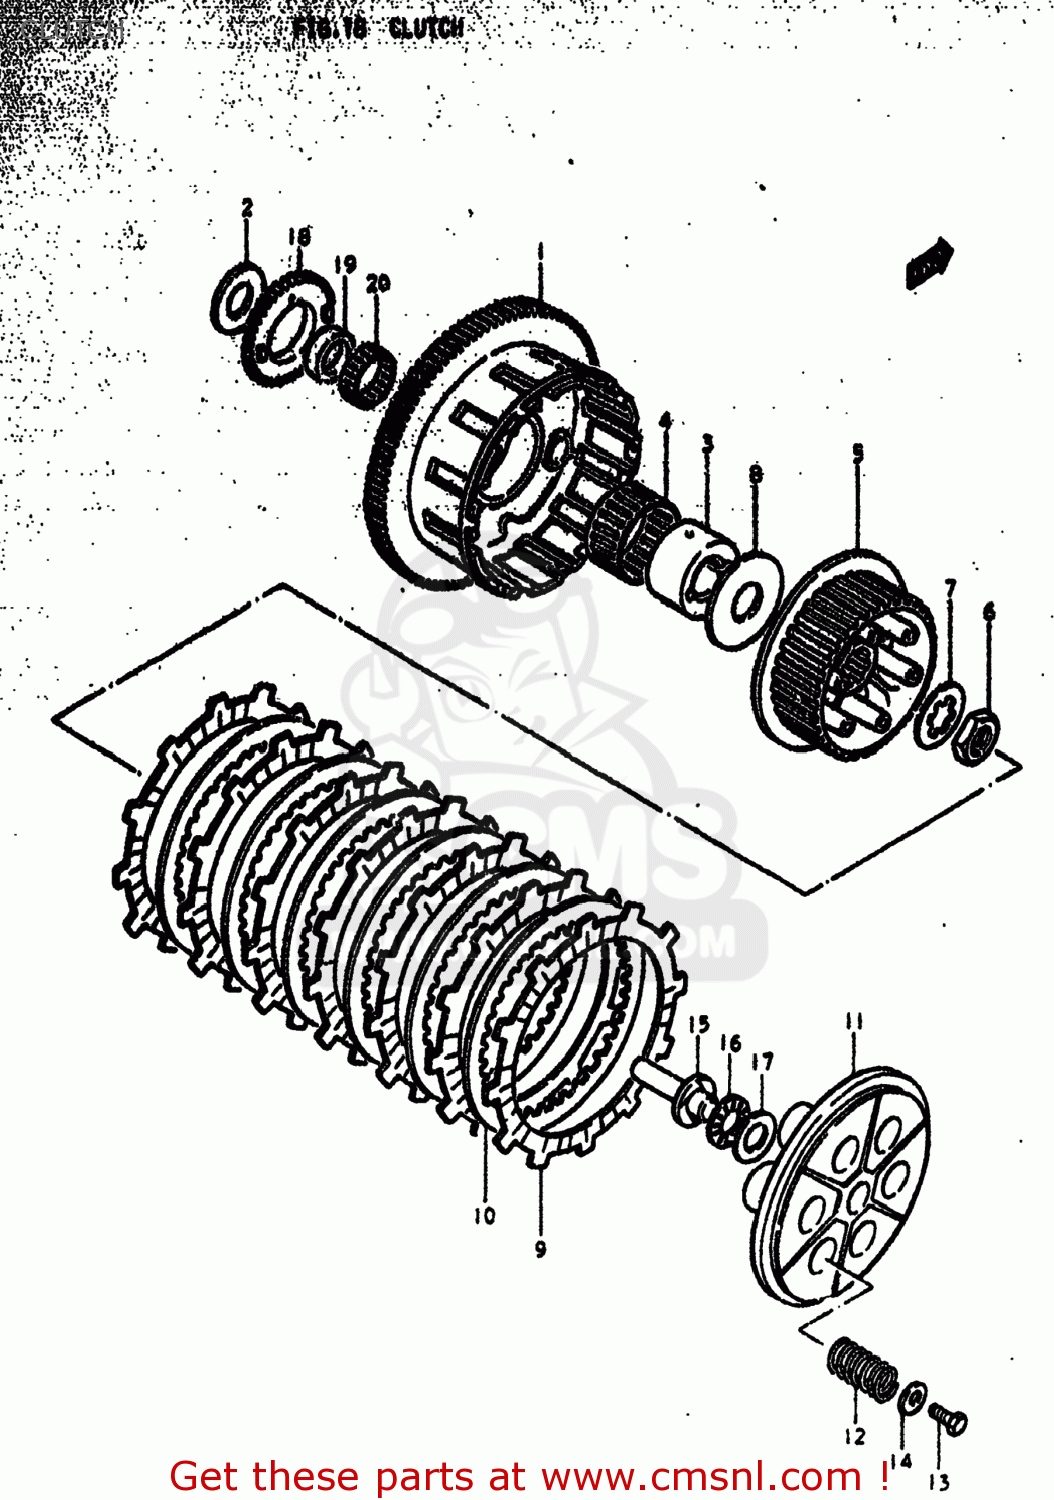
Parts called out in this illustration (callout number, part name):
1	GEAR ASSEMBLY,PRIMARY DRIVE
2	WASHER
3	SPACER,PRIMARY DRIVEN
4	BEARING
5	HUB,CLUTCH SLEEVE
6	NUT
7	WASHER,LOCK
8	WASHER(25X66X3.5)
9	PLATE,CLUTCH DRIVE (NAS)
10	PLATE,CLUTCH DRIVEN (NAS)
11	DISC,CLUTCH PRESSURE
12	SPRING
13	BOLT, UPPER
14	WASHER
15	PIECE,CLUTCH PUSH
16	BEARING(15X28X2)
17	WASHER
18	GEAR,OIL PUMP DRIVE
19	SPACER,OIL PUMP DRIVE GEAR
20	BEARING(36X40X10)
